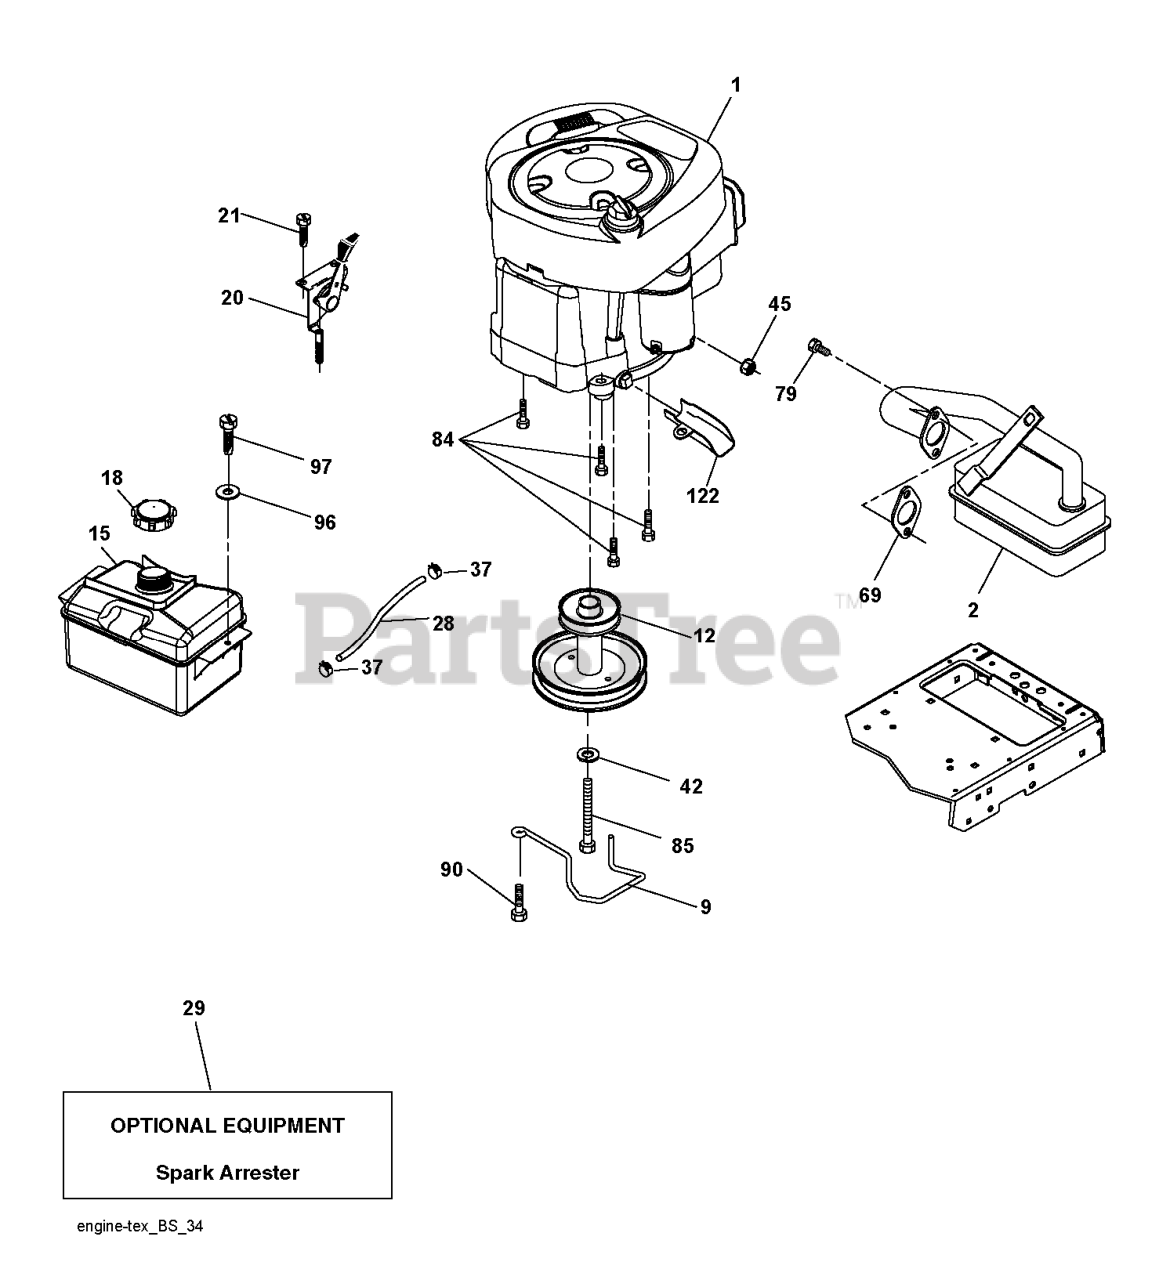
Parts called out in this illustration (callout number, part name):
2	MUFFLER.B&S.MODEL.21.11HP.OHV
9	KEEPER.BELT.ENGINE.3.25 (3 2)
12	PULLEY.ENG.CL.MECH.SLVR.LT/YT
15	RP TANK FUEL FRT 1.5 GAL
18	CAP.FUEL.2.25"VENTED"
20	CONTROL.TH/CK.C.
21	SCREW.#10 X 0.750.BOS
28	LINE.FUEL.20
29	KIT.SPARK ARRESTOR 794945 B&S
37	HOSE CLAMP
42	LOCKWASHER
45	NUT
69	REPL BY 532 27 22-93
79	SCREW.SOCKET HD.5/16-1
84	SCREW.3/8-16
85	BOLT HEX 7/16-20X4-1/4"
90	SCREW 3/8-16X1
97	SCREW HEXWSHR 1/4-20X3/4
122	EXTENSION DRAIN OIL
